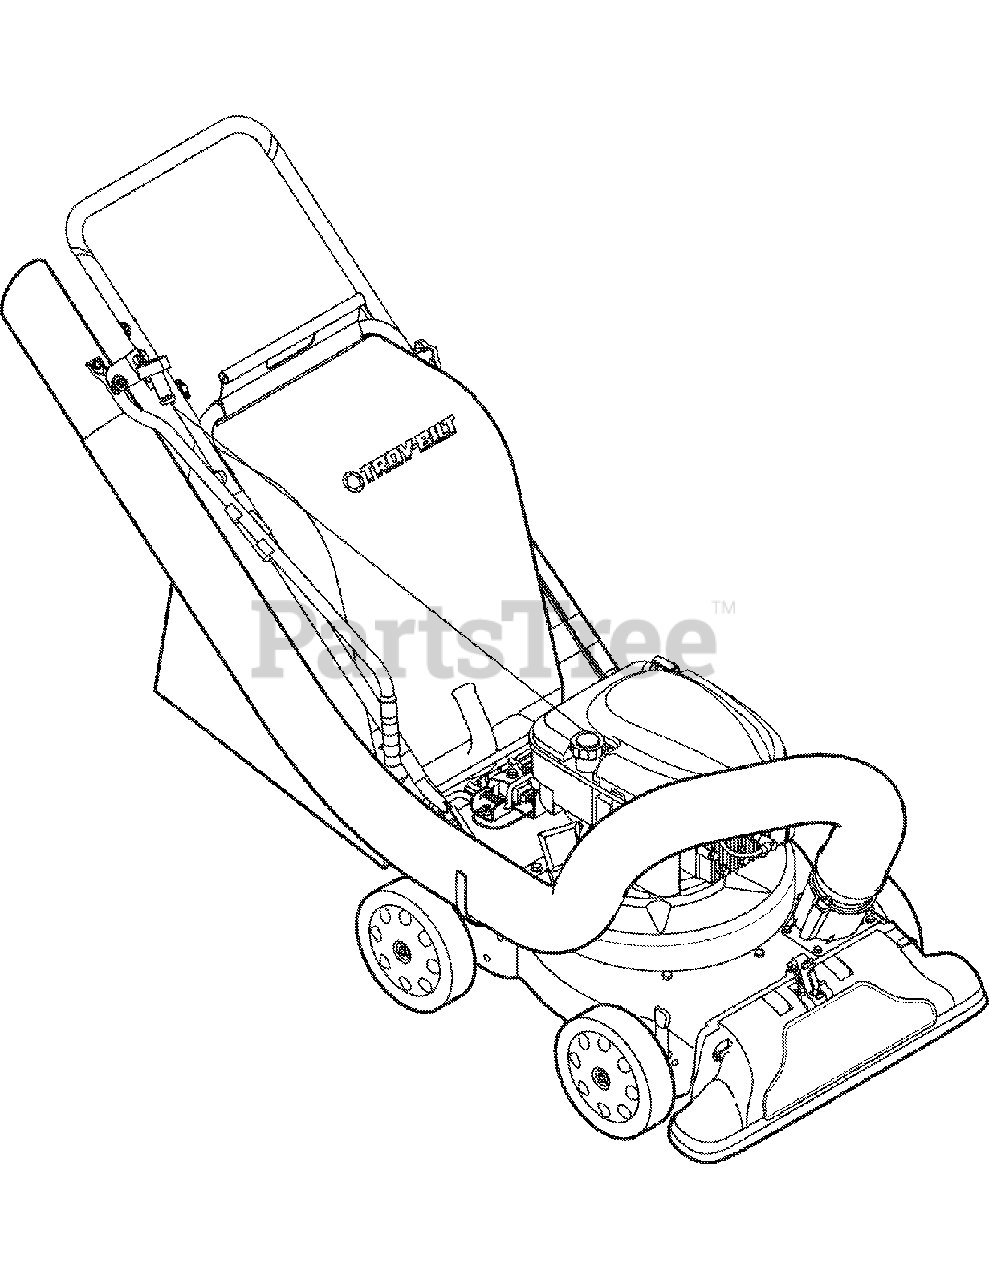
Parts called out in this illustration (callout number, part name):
NA	Drive Belt
NA	Drive Control Cable
NA	Speed Control Cable
NA	Hubcap
